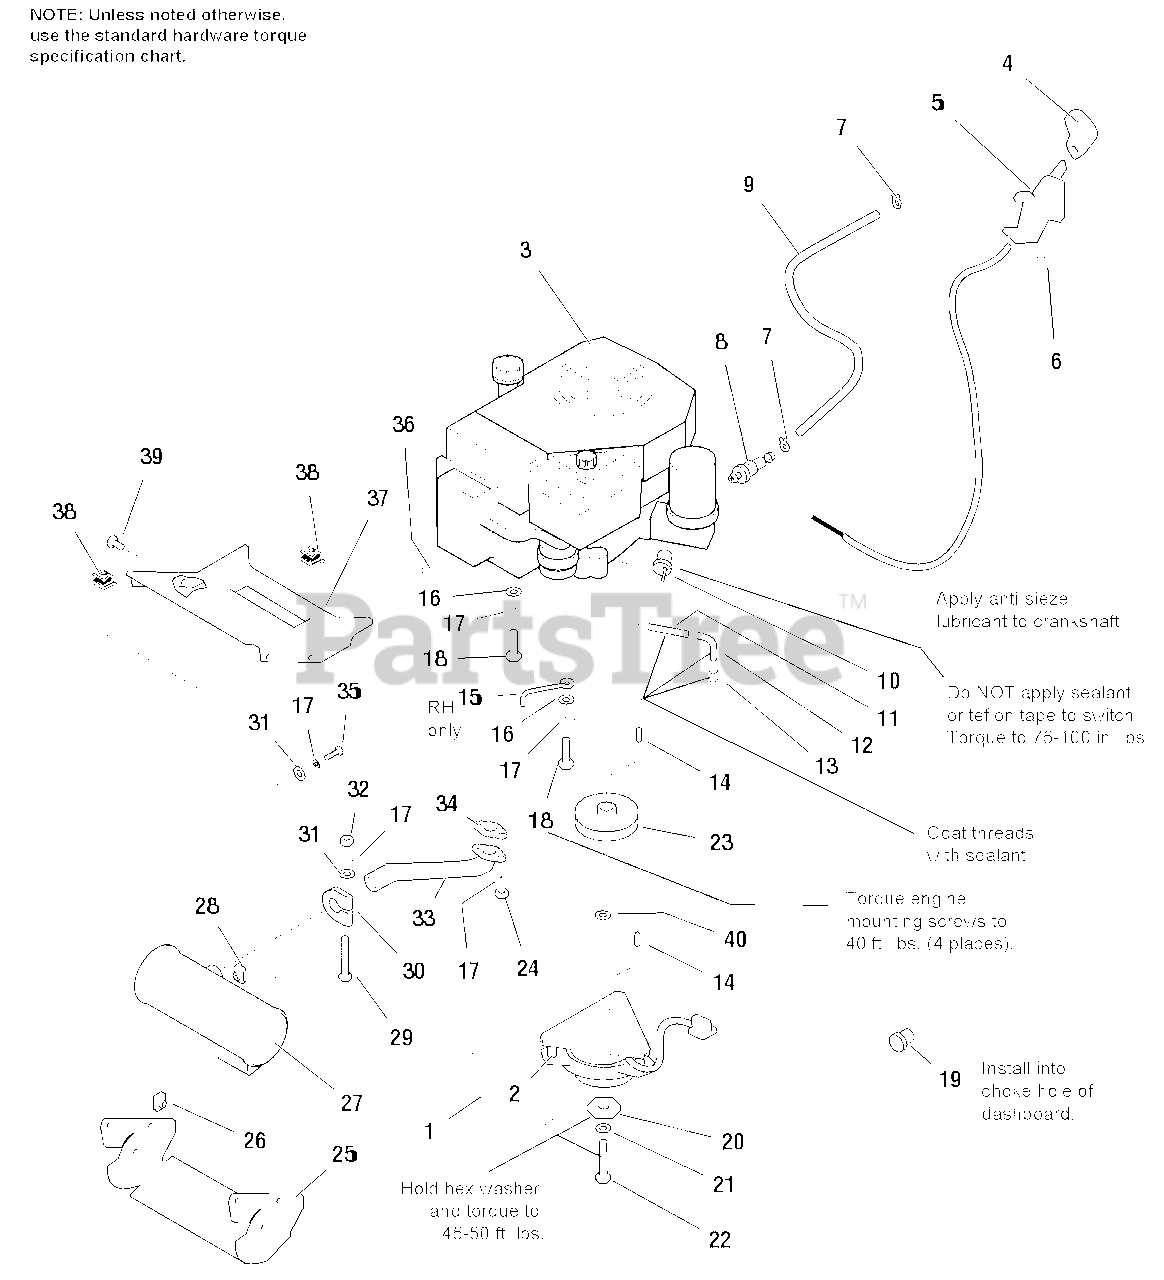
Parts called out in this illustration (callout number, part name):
1	ELECTRIC CLUTCH
2	SPRING & NUT KIT
3	ENGINE, 16HP Kohler Command
4	KNOB, Throttle
5	THROTTLE CONTROL ASSY.
6	CAPSCREW, Hex Washer Hd, Plastite, 1/4-20 x 1/2
7	CLAMP, Hose
8	FUEL FILTER
9	HOSE, Fuel, 45-1/2" Long
10	SWITCH, Oil Pressure
11	PIPE NIPPLE, 3/8 x 2
12	STREET ELBOW, 3/8 Pipe
14	KEY, Hi-Pro
16	WASHER, Flat, 5/16
17	LOCKWASHER, 5/16
18	CAPSCREW, Taptite, M8-1-1/4 x 30 mm
19	FASTENER, Panel
20	WASHER, Hex
21	LOCKWASHER, 7/16
22	CAPSCREW, 7/16-20 x 2-1/2
23	PULLEY ASSY
24	NUT, Exhaust
25	DUCT, Lower Muffler
26	PAL NUT, 1/4-20
27	MUFFLER ASSY.
28	PAL NUT, 5/16-18
29	CARRIAGE BOLT, 5/16-18 x 2-3/4
30	CLAMP, Muffler
31	WASHER, 5/16
32	NUT, Hex, 5/16-18
33	PIPE, Exhaust
34	GASKET, Exhaust
35	CAPSCREW, Hex Hd, 5/16-18 x 1
36	LOCKWASHER, External Tooth, 5/16
37	DUCT, Top, Muffler
38	CLIP
39	CAPSCREW, Hex Flange Hd, Whizlock, 1/4-20 x 5/8
40	WASHER
